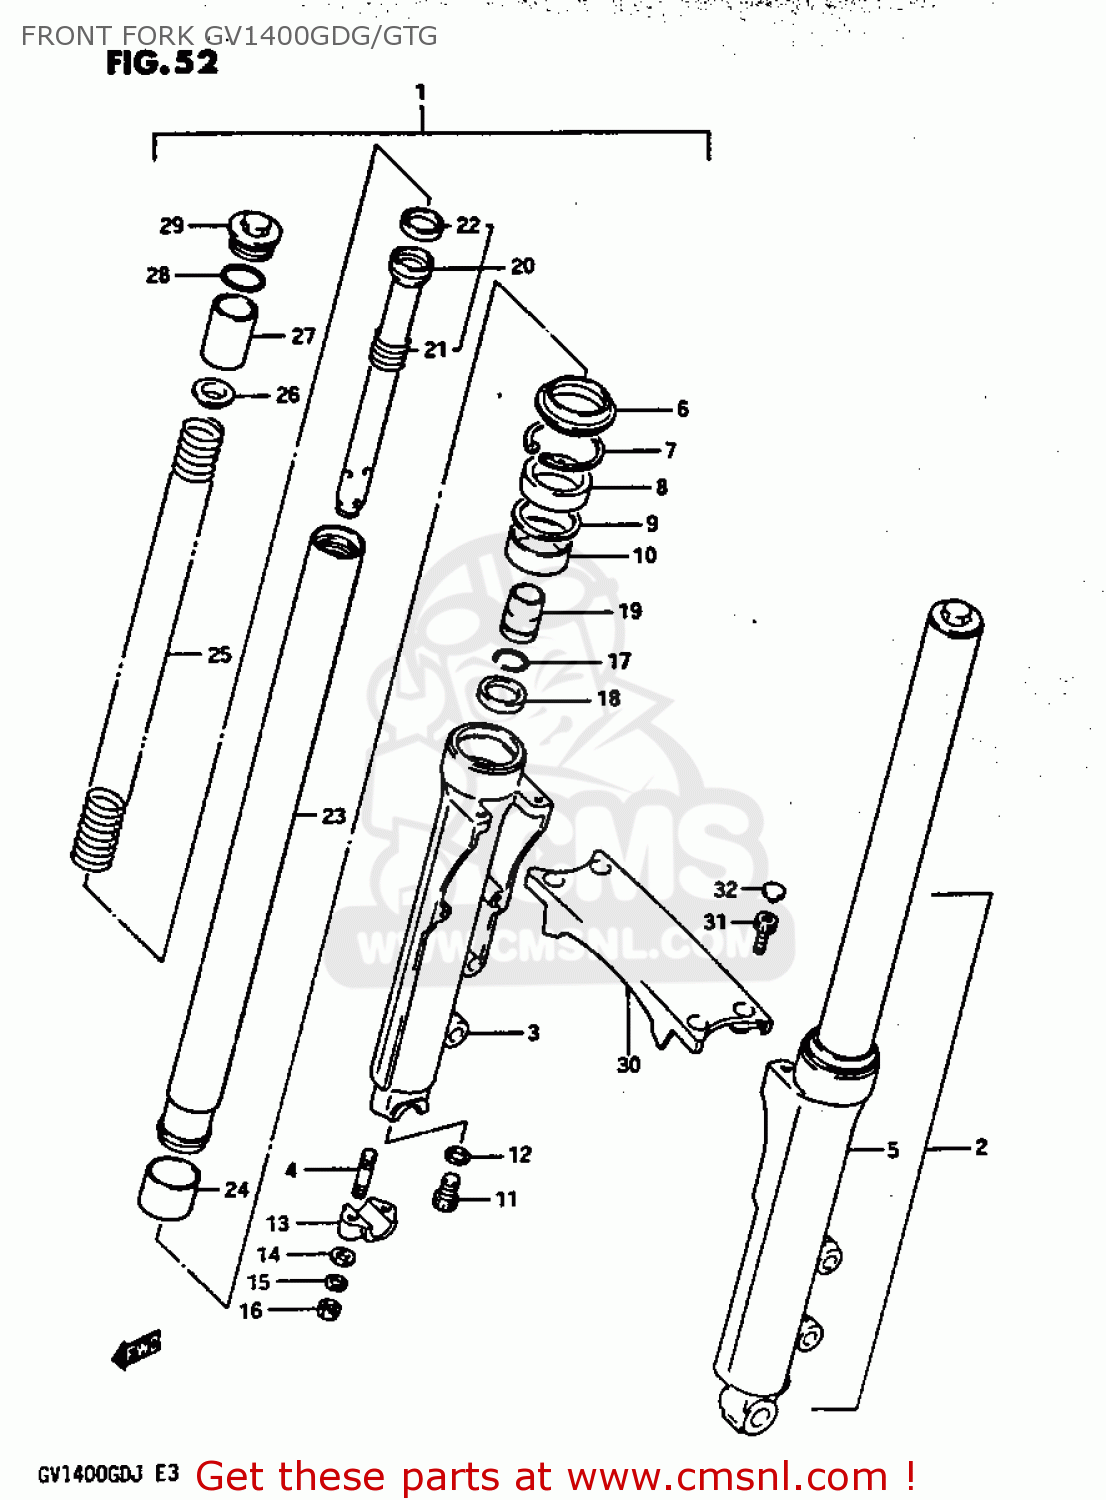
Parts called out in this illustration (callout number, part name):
1	DAMPER ASSEMBLY,FRONT FORK,RIGHT
2	DAMPER ASSEMBLY,FRONT FORK,LEFT
3	TUBE,OUTER,RIGHT
4	STUD 8X30
5	TUBE,OUTER,LEFT
6	DUST SEAL,FRONT FORK
7	RING,OIL SEAL STOPPER
8	OIL SEAL,FRONT FORK
9	WASHER,FORK OIL SEAL
10	METAL,SLIDE
11	BOLT,CYLINDER
12	GASKET,CYLINDER (NAS)
13	HOLDER,AXLE
14	WASHER
15	LOCK WASHER
16	NUT (8MM)
17	RING,SNAP
18	VALVE
19	PIECE,OIL LOCK
20	CYLINDER
21	SPRING,REBOUND
22	RING,PISTON
23	TUBE,INNER
24	METAL,SLIDE FR FORK
25	SPRING
26	GUIDE,SPRING
27	SPACER,SPRING
28	O RING
29	BOLT,FORK
30	BRACE,FORK
31	BOLT
32	CAP(OD:14.5)
